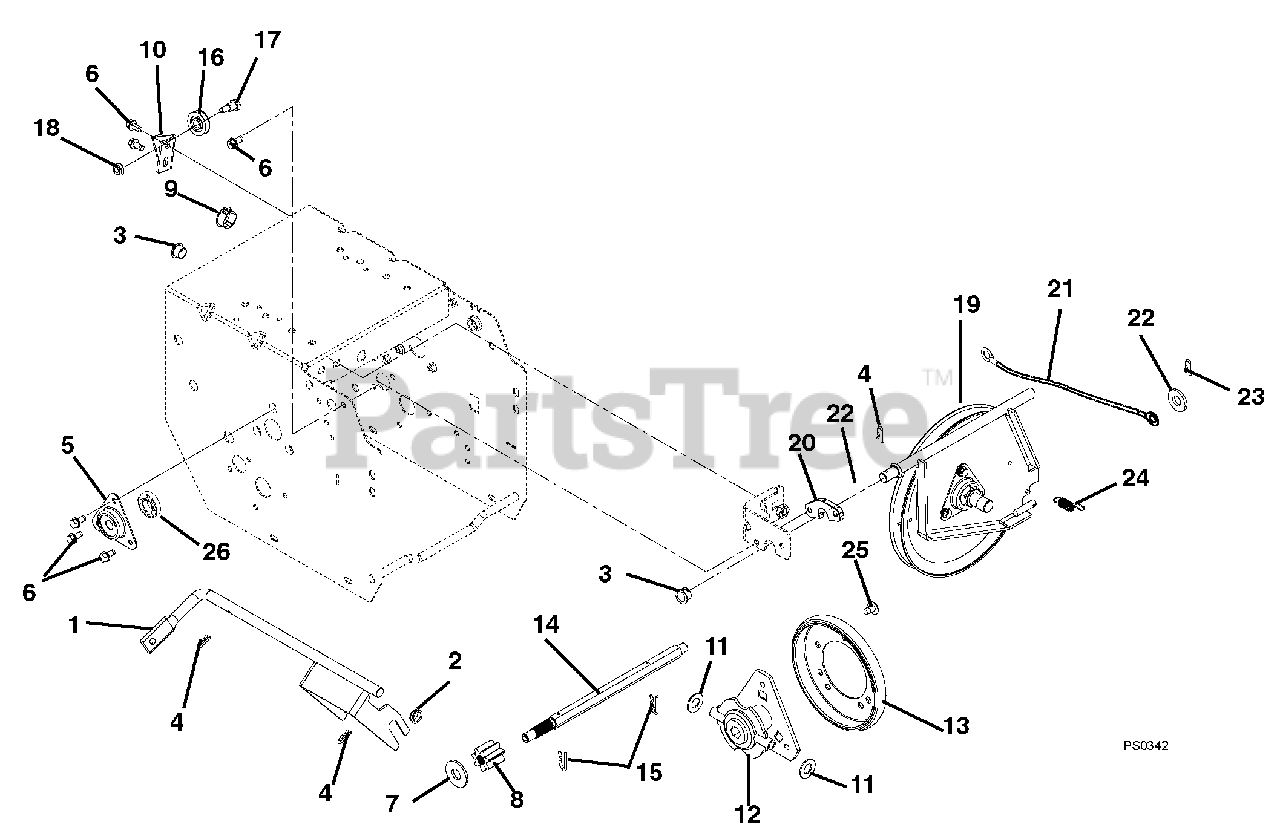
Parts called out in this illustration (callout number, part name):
1	WELDMENT, SHIFT FORK
2	BUSHING, POLYLINER-.50 SNAPIN
3	BUSHING, POLYLINER-.50 SPLIT
4	CLIP, SPRING
5	FLANGE, BEARING
6	SCR-TAP .25-20X.50 HWH TR YWZ
7	@WSHR-FL-STL.563X1.38X.109YWZC
8	GEAR, PINION, 7 TOOTH W/SPLINE
9	PLUG, HOLE - .875" NYLON
10	BRACKET, CABLE PULLEY
11	WSHR-FL-STL .505X1.00X.062YWZC
12	CARRIER, DRIVE DISK
13	FRICTION, DISC
14	SHAFT, HEX W/SPLINE
15	PIN, SPRING CLIP
16	PULLEY, CABLE
17	BOLT, SHLDR-.375X.375X.25-20
18	@NUT-LK-TOP-FLG .25-20 YWZC
19	PLATE, SWING - ASSEMBLY
20	SPACER, SWING GATE
21	CABLE, TRACTION - TRACTOR
22	@WSHR-FL-STL.344X.688X.065YWZC
23	PIN-HAIR INT .08X.18X1.18 YWZC
24	SPRING, EXT. .043X.438X1.64
25	SCR-TAP SERRDHDTX .31-18X.50BP
26	BRG-BALL .437X1.375X.437
